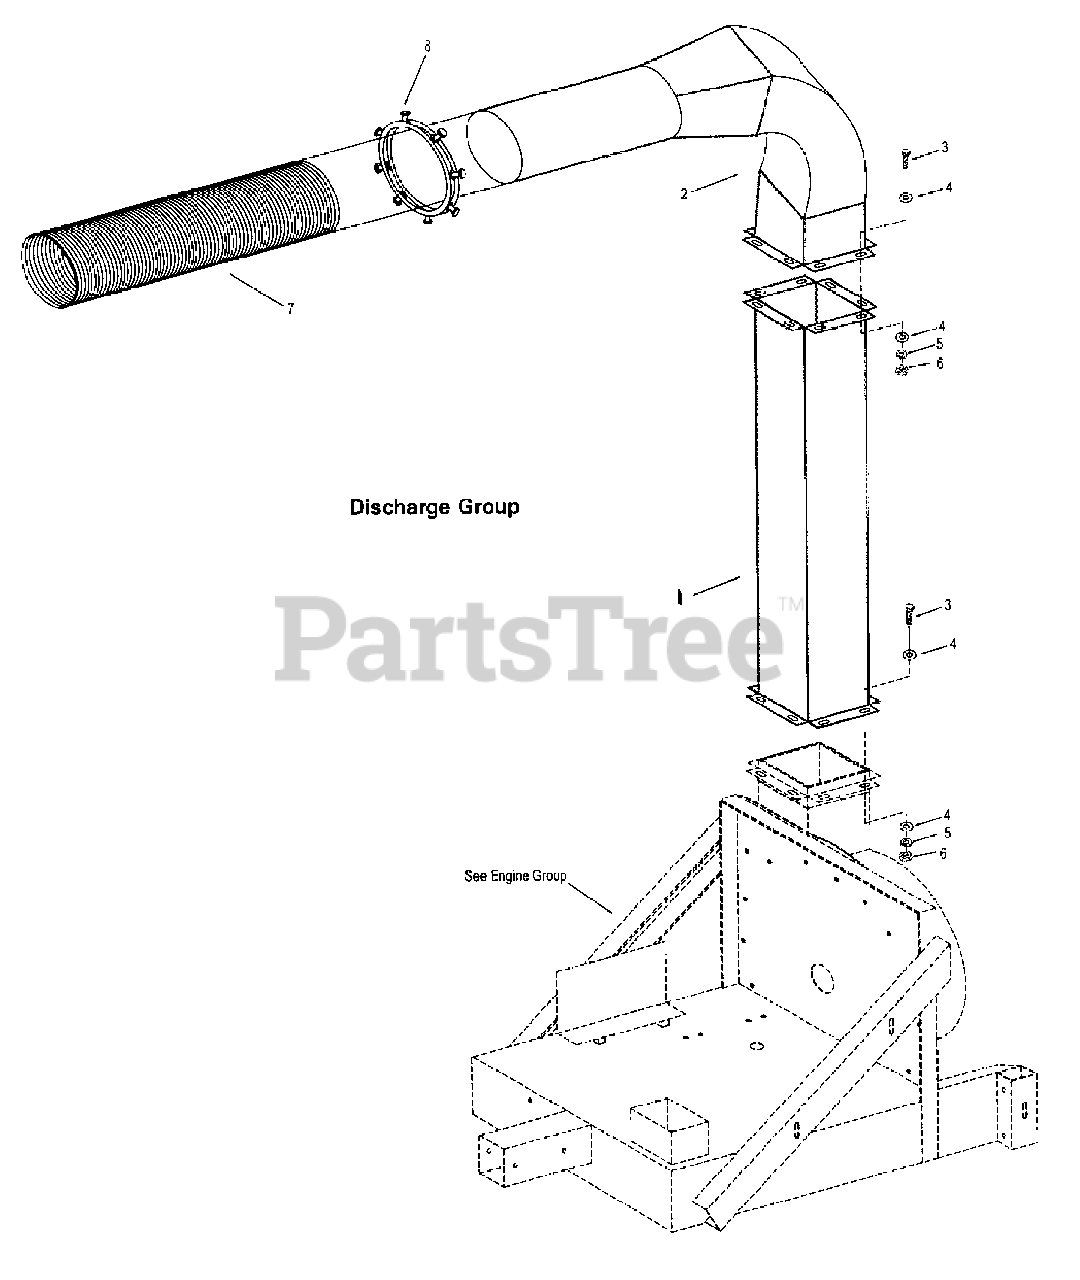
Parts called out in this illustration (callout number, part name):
1	Discharge Stack
2	Discharge Elbow
3	3/8-16 x 1-1/4" Hex Bolt
4	3/8 Flat Washer
5	3/8 Lock Washer
6	3/8-16 Hex Nut
7	Hose, Discharge 8" x 5' Metal
8	Ring, Squeeze 8"
